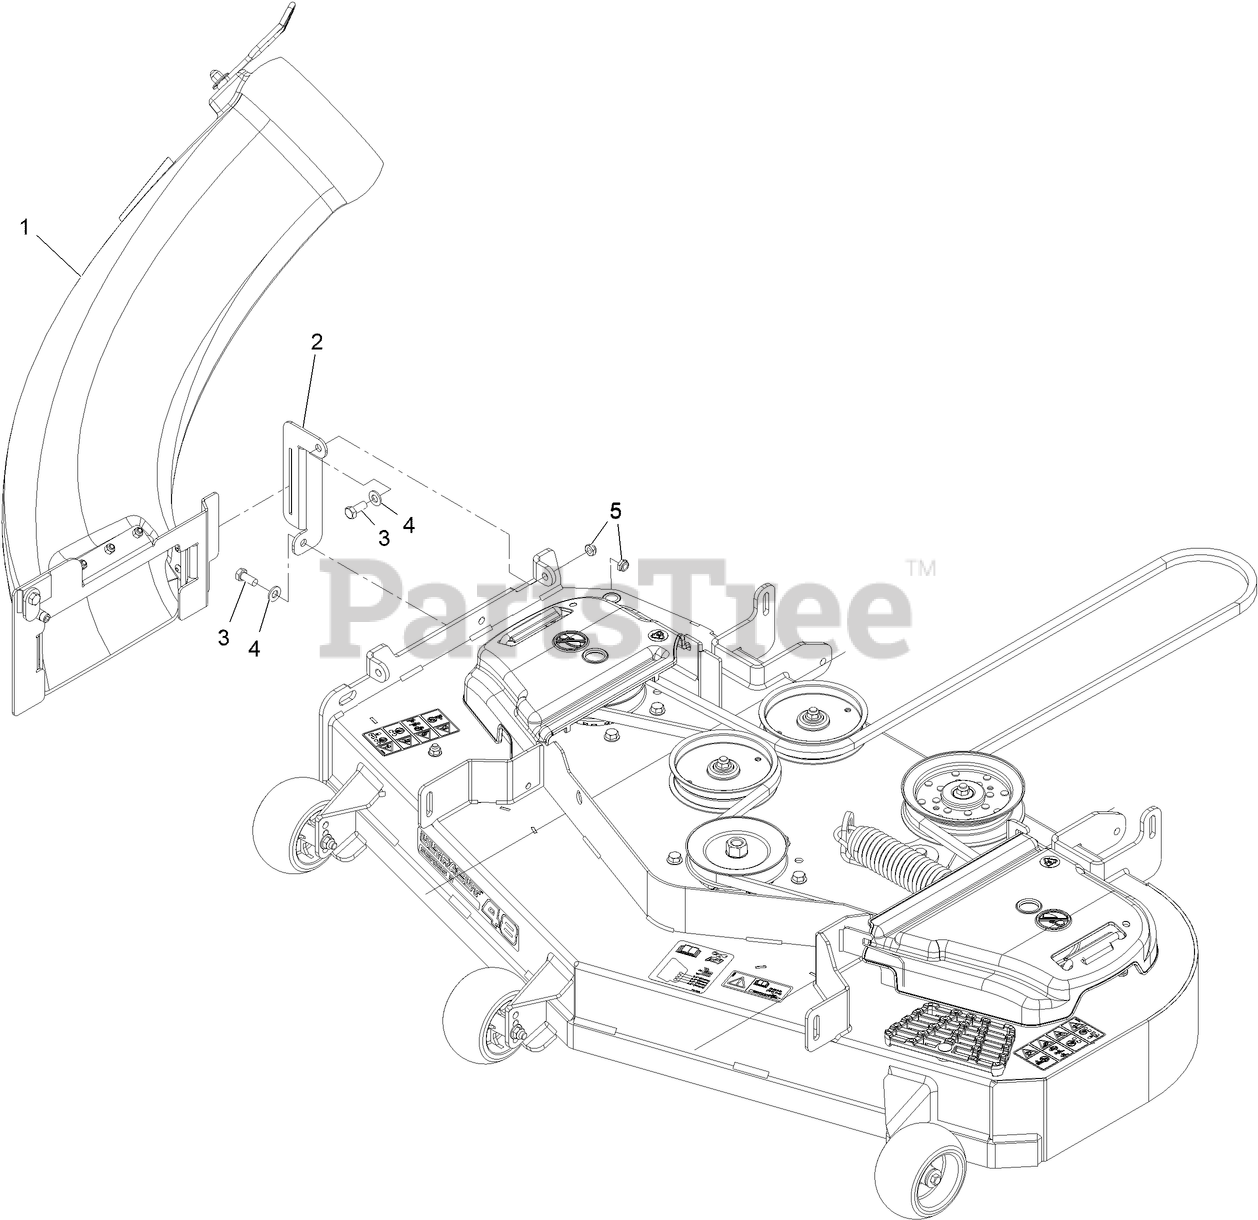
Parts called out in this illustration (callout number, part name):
1	48 IN BAGGER BOOT ASM
2	BRACKET-BOOT MOUNT
3	SCREW-HH
4	WASHER-FLAT
